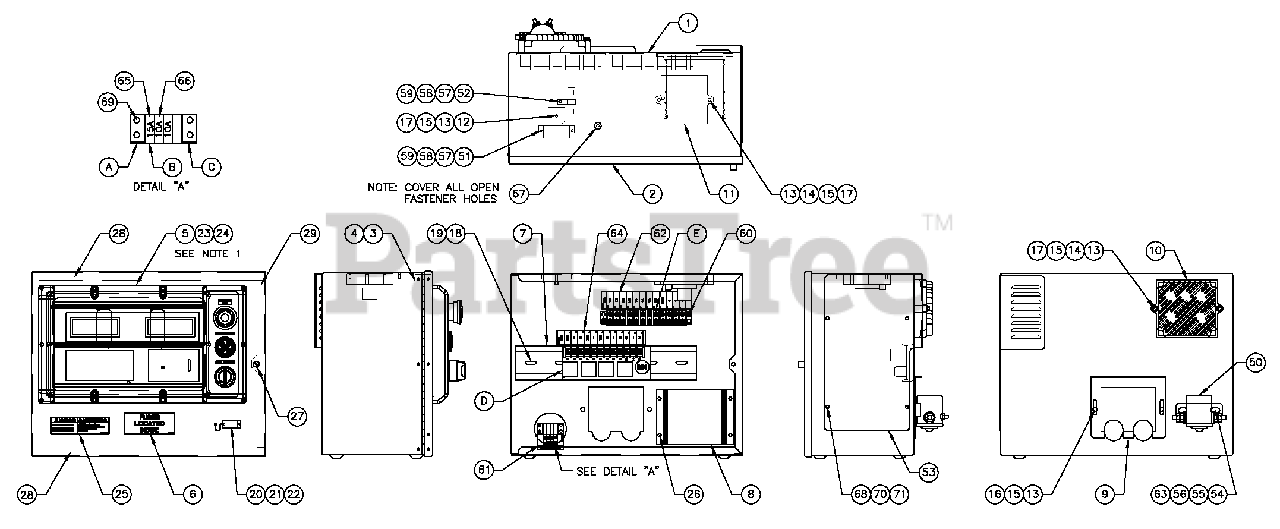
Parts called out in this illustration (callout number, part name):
1	ENCL H/G CONTROL PANEL
2	COVER CONTROL PANEL
3	HINGE CONTINUOUS H PANEL
4	RIVET POP .125 X .275 SS
5	ASSY PROGRAMMED H-100
6	DECAL FUSES LOCATED INSIDE
7	RAIL SNAPTRACK PCB HOLDER BULK (12" LG)
8	ASSY PCB 2AMP 12V UL BATT CHGR
9	PLATE HARNESS CLAMP
10	ASSY PCB PWR AVR W/AMP HEADER
11	ASSY PCB BOSCH GOV DRIVER
12	DIO BRIDGE 25A 600V
13	WASHER LOCK M5
14	SCREW PPHM M5-0.8 X 30 SS
15	WASHER FLAT M5
16	SCREW HHPM M5-0.8 X 12
17	NUT HEX M5-0.8 G8 YEL CHR
18	WASHER FLAT M4
19	SCREW PHTT M4-0.7 X 10 ZYC
20	CONN DUST CAP W/CHAIN DB9
21	WASHER FLAT M3.5
22	SCREW PHTT M3.5-0.6X 10
23	SCREW PPHM M4-0.7 X 8 BLX OX
24	WASHER LOCK #8-M4
25	DECAL WRN BATT CHRG 12/24V BI
26	SCREW PHTT M4-0.7 X 12 ZYC
27	M5-0.8 CAPTIVE PANEL KNLD HD
28	SEAL COVER 3.18 X 12.7 X 382
29	SEAL COVER 3.18 X 12.7 X 283
50	RELAY CONTACTOR 12VDC
53	COVER CONTROL PANEL SIDE
54	SCREW HHC 1/4-20 X 3/4 G5
55	WASHER FLAT M6-1/4
56	WASHER LOCK M6-1/4
57	WASHER LOCK M3
58	NUT HEX M3-0.5 G8 YEL CHR
59	WASHER FLAT M3
60	SCREW PHTT #6-32 X 5/8 ZYC
61	DECAL CPL CONTROL PANEL FUSES
62	DECAL CPL 5.4/6.8L TB3
63	NUT HEX 1/4-20 STEEL
64	DECAL CPL 5.4/6.8L RELAY BOARD
65	FUSE ATO TYPE 15 AMP (BLUE)
66	FUSE ATO TYPE 10 AMP (RED)
67	SEAL WEATHER .45"DIA
68	SCREW PPHM M5-0.8 X 12 ZNC
69	SCREW PHTT #6-32 X 3/8 ZYC
70	WASHER FLAT M5
71	WASHER LOCK M5
A	ADPTRRH SIDE WICKMANN 178.6191
B	HOLDER FUSE WICKMANN 178.6150
C	ADPTR LH SIDE WICKMANN 178.6192
D	ASSY PCB G-PANEL RELAY 12VDC
E	BLOCK TERM 20A12 X 6 X 1100V
